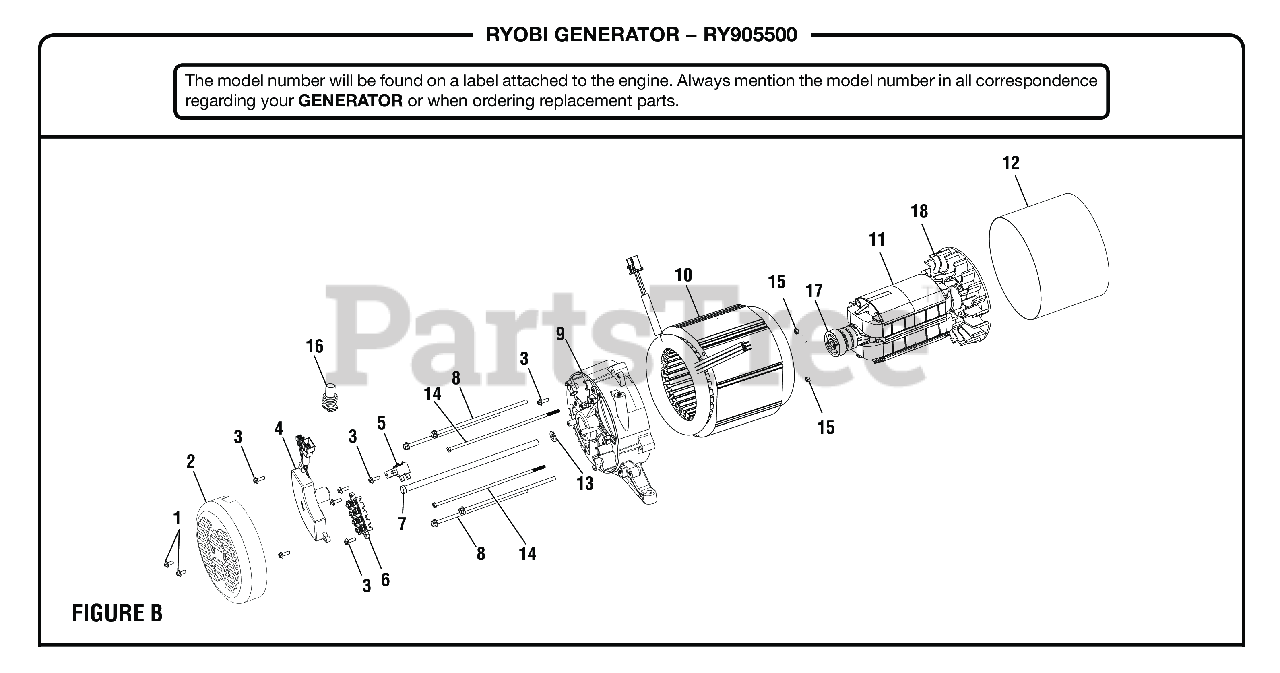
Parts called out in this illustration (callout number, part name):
1	Bolt (M5 x 12 mm, Hex Flange Hd.)
2	Brush Cover
3	Bolt (M5 x 16 mm, Hex Flange Hd.)
4	Automatic Voltage Regulator
5	Brush Assembly 190 mm
6	Terminal Block
7	Rotor Bolt (M8 x 222 mm, Flange Hex Hd.)
8	Stator Bolt (M6 x 180 mm, Flange Hex Hd.)
9	Bearing Support
10	Stator Assembly
11	Rotor Assembly
12	Generator Head Cover
13	Washer (ID8.4 x OD25.1 x 3t)
14	Bolt (M5 x 200 mm, Hex Hd.)
15	Hex Nut (M5)
16	Rubber Sleeve
17	Ball Bearing (190 mm)
18	Fan (190 mm)
